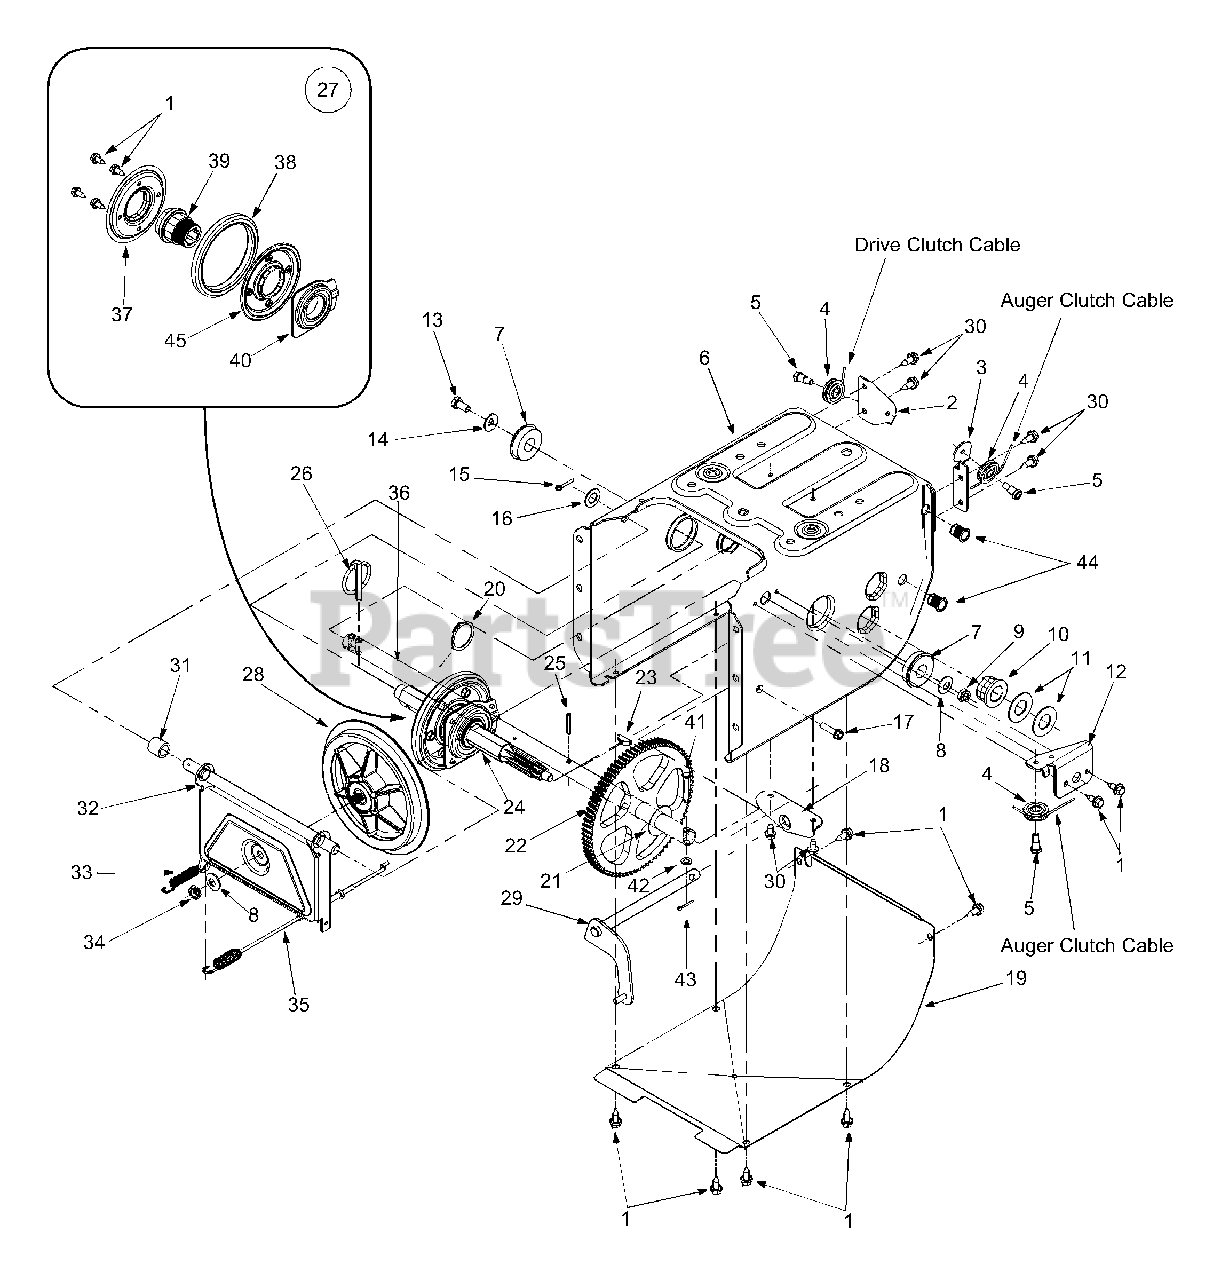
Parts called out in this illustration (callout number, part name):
1	Self-tapping Screw, 1/4-20 x.625
5	Hex Screw 1/4-28
6	Frame Assembly
7	Ball Bearing
8	Bell Washer
9	Lock Jam Nut
10	Hex Flange Bearing
11	Flat Washer
14	Bell Washer.340 ID x.872 OD
15	Cotter Pin
16	Flat Washer.536 ID x.930 OD
17	Self-tapping Screw, 1/4-20 x 1.25
21	Flat Washer.760 ID x.50 OD
22	80 Tooth Gear
24	7-Tooth Shaft
25	Roll Pin
26	Klik Pin
27	Friction Wheel Assembly
28	Friction Disc Wheel
29	Wheel Shift Rod Assembly
30	Self-tapping Screw, 1/4-20 x.5
31	Spacer
34	Jam Nut 3/8-24
35	Drive Cable
36	Axle 13" Wheels
37	Friction Plate
38	Friction Wheel Rubber
39	Friction Wheel Hub
40	Friction Wheel Bearing Assembly
41	Clevis Pin, 1/4 x 1.3725
42	Flat Washer,.281 x.5 x.063
43	Cotter Pin,.75
44	Insert Nut, 5/16-18
45	Friction Plate
